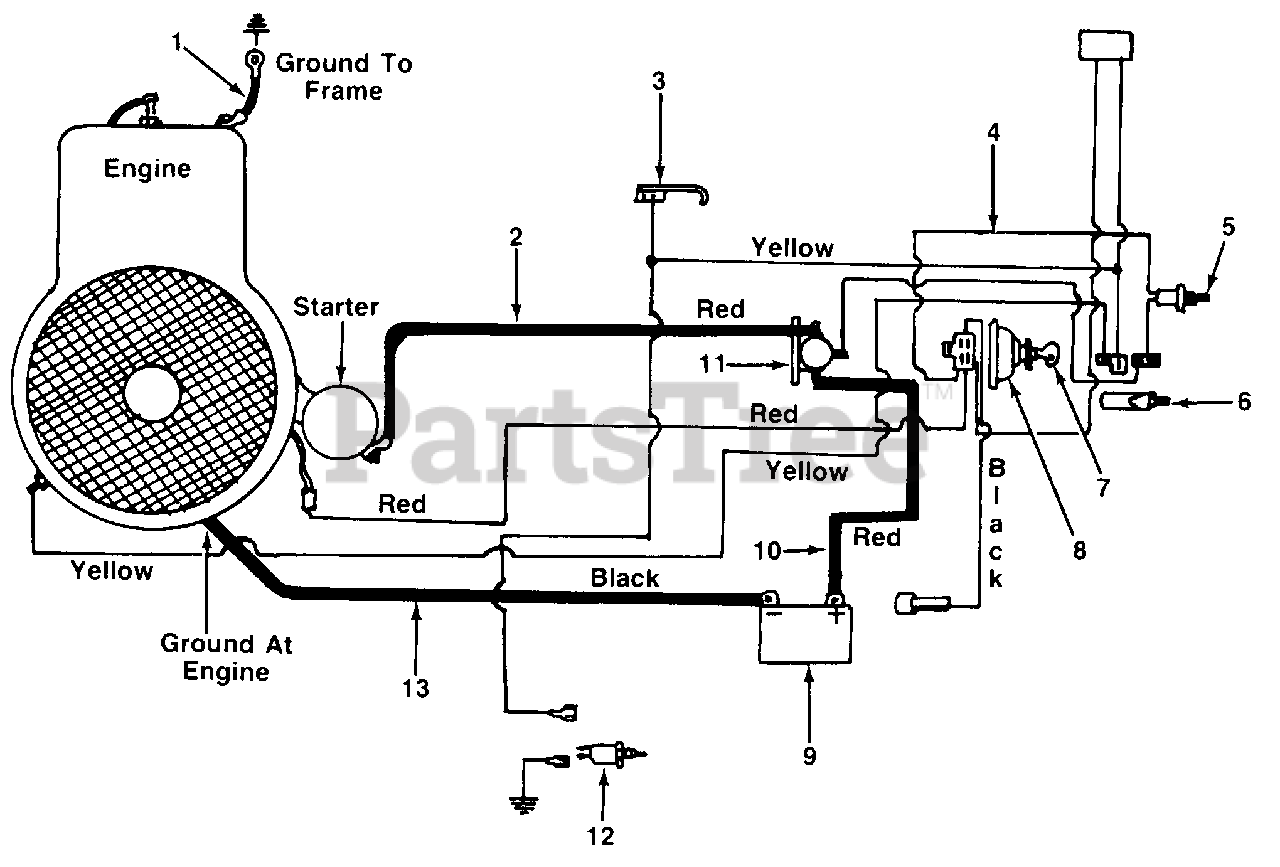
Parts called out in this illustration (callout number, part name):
1	Elec. Wire 8 Ga. x 9.0" Lg.
2	Elec. Wire
3	Spring Switch Reverse
4	Wire Harness
5	Safety Switch Black N.O.
6	Safety Switch
7	Ignition Key
8	Ignition Switch
9	Battery 12V
10	Elec. Wire 8 Ga. x 11.5" Lg. Black
11	Solenoid
12	Safety Switch Red N.C.
13	Elec. Wire 8 Ga. x 9.0" Lg.
